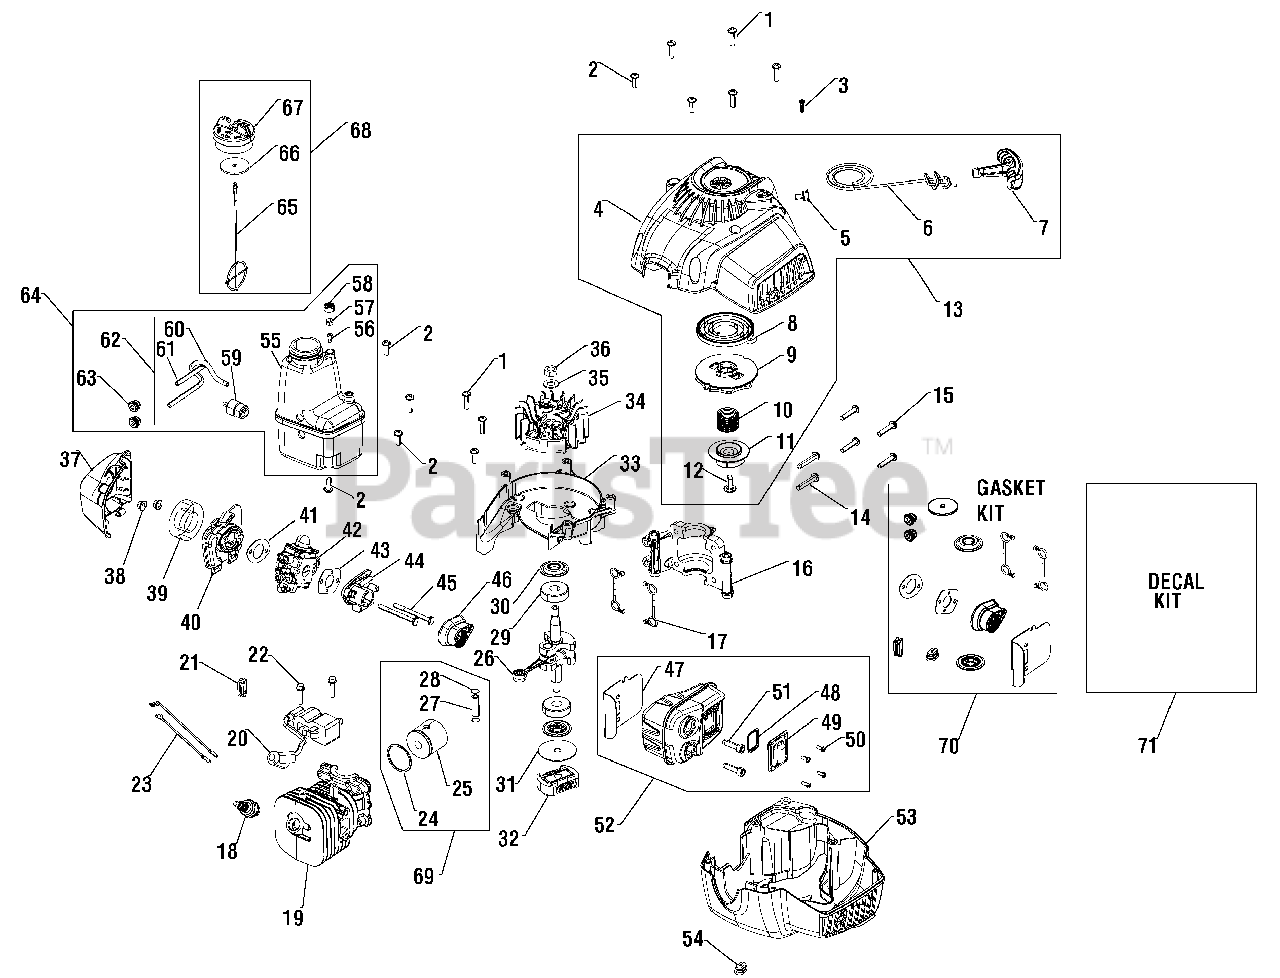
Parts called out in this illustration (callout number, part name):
4	Engine Housing Top
5	Eyelet, Starter Rope
6	Rope, Starter
7	Handle, Starter
8	Recoil, Spring
9	Starter Pulley
10	Spring, Starter
11	Starter Hub
12	Screw
13	Starter Housing Assy.
14	Screw
16	Cap, Bearing
17	Seal, Cylinder
18	Spark Plug (RCJ-6Y)
19	Kit -Cyl./Flywheel Scroll
20	Ignition, Module
21	Grommet, Cable
23	Coil Wire
24	Piston Ring
25	Piston
26	Kit - Crankshaft Assy.
27	Piston Pin
28	Retainer, Wrist Pin
30	Seal, Crankshaft
31	Gasket, Clutch
32	Kit - Clutch
33	Kit - Cyl./Flywheel Scroll
34	Flywheel Assembly
35	Washer
36	Nut
37	Air Filter Cover
40	Air Filter Support
42	Kit - Carburetor
44	Plate Carb
46	Boot, Carb
48	Screen, Spark Arrestor
49	Hood, Exhaust Outlet
52	Muffler Assembly
53	Engine Housing, Lower
54	Grommet
55	Fuel Tank
56	Valve
57	Foam
58	Cover, Valve
59	Fuel Filter
60	Fuel Tube, Inlet
61	Fuel Tube, Outlet
62	Kit - Fuel Line
63	Grommet, Fuel Tube
64	Kit - Fuel Tank Assy.
65	Retainer
66	Gasket
67	Fuel Cap
68	Fuel Cap Assembly
69	Piston Kit
70	Kit - Gasket
71	Kit - Decal
